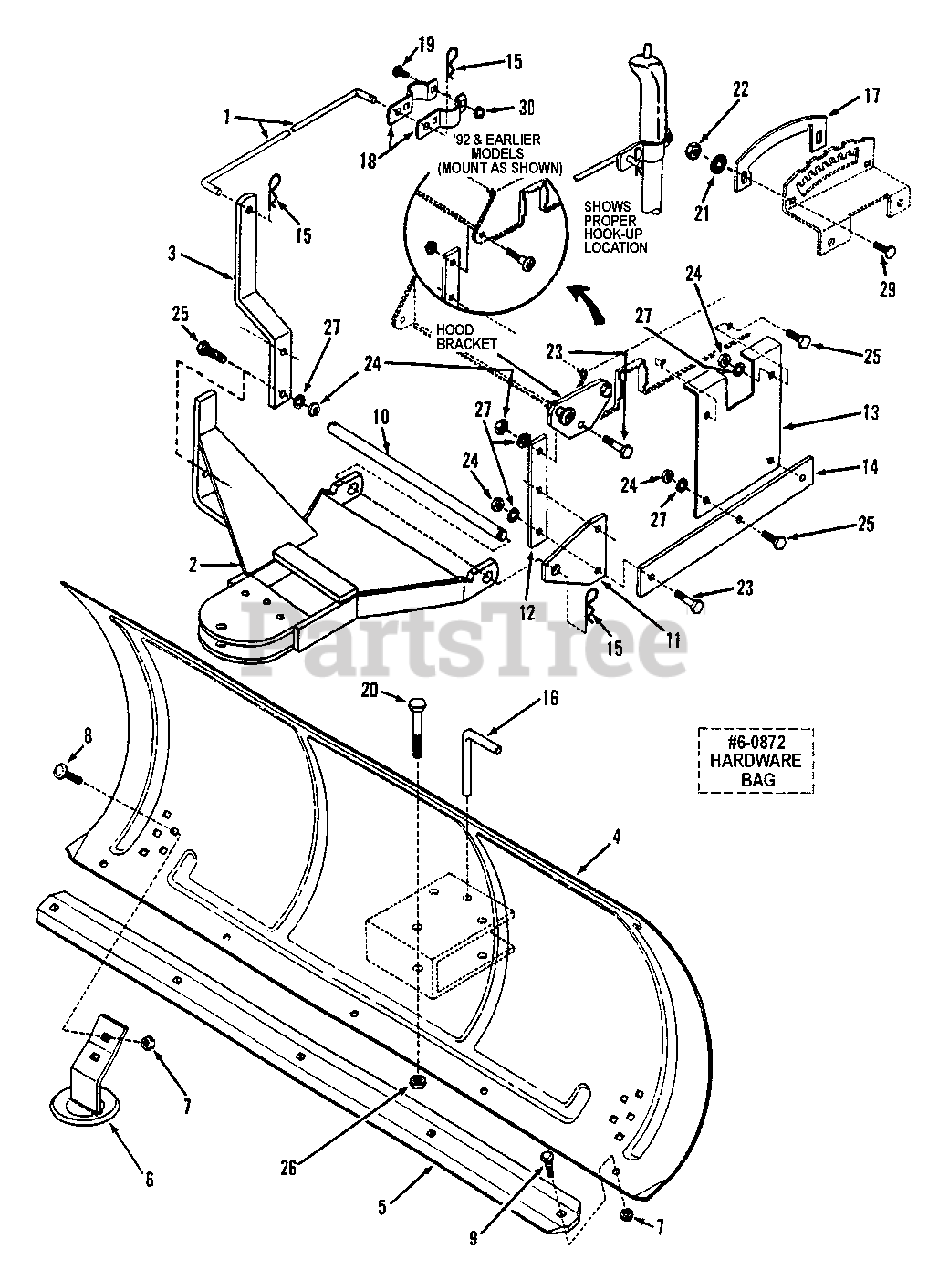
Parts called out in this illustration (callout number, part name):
1	ROD, Lift
2	WELDMENT, Bracket, 36/42 Snow Blade
3	EXTENSION, Lift, 36/42 Snow Blade
4	WELDMENT, 42" Blade
5	SCRAPER
6	WELDMENT, Slide
7	NUT, 3/8-15 Hex Center Lock, Grade 5 or B
8	BOLT, 3/8-16 x 1" Square Neck Carriage, Grade 2
9	BOLT, 3/8-16 x 3/4" Short Neck Carriage, Grade 2
10	PIN, Holding
11	BRACKET, Mount
12	BAR, Hanger
13	PLATE, Hanger
14	TIE BAR, Side
15	HAIR PIN, 3/32 x 1-1/8"
16	PIN
17	PLATE, Lockout
18	TAB, Lift Lever
19	BOLT, 1/4-20 x 1/2" Short Neck Carriage, Grade 5
20	SCREW, 1/2-20 x 2-3/4" Hex Head Cap, Grade 5
21	WASHER, 1/4" Internal Tooth Lock
22	NUT, 1/4-20 Hex
23	SCREW, 3/8-16 x 1-1/4" Hex Head Cap, Grade 5
24	NUT, 3/8-16 Hex
25	SCREW, 3/8-16 x 1" Hex Head Cap, Grade 5
26	NUT, 1/2-20 Hex Center Lock
27	WASHER, 3/8" Internal Tooth Lock
29	BOLT, 1/4-20 x 5/8"
30	NUT, 1/4-20 Hex Flange Lock
